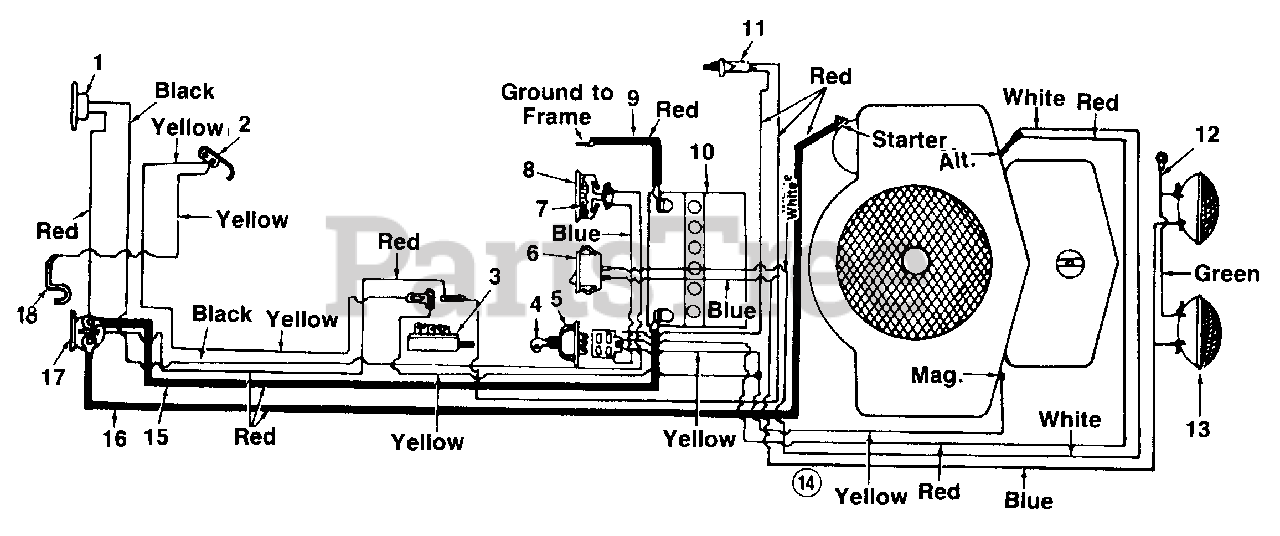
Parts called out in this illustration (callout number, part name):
1	Circuit Breaker
2	Spring Switch
3	Safety Switch Dpst.
4	Ignition Key
5	Ignition Switch
6	Headlight Switch
8	Ammeter
9	Grounding Wire 14.0" Lg.
10	12 Volt Battery
11	Safety Switch
12	Ground Wire
13	Headlight
14	Wire Harness
15	Electric Wire 27.0" Lg.
16	Electric Wire 32.5" Lg.
17	Solenoid
18	Spring Switch
